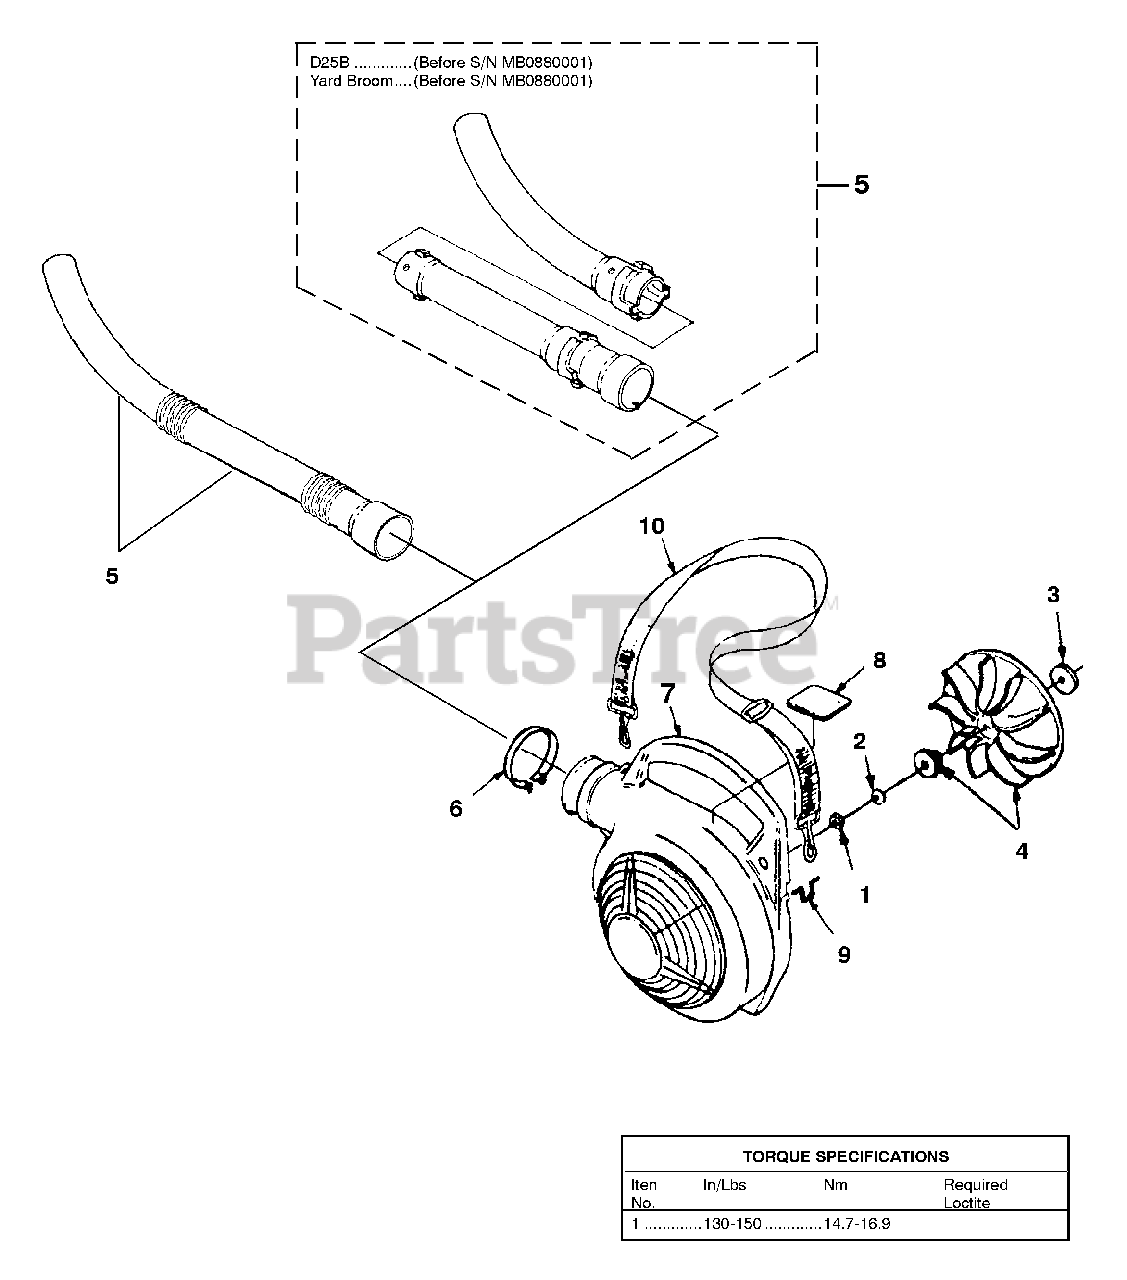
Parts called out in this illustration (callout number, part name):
1	NUT-Hex (3/8-24)
2	WASHER-Bellville (3/8")
3	WASHER-Flat
4	BLOWER FAN KIT
6	CLAMP w/Fasteners
7	VOLUTE HOUSING (Outer)
8	DECAL-Warning
9	LOOP-Wire
10	SHOULDER STRAP
